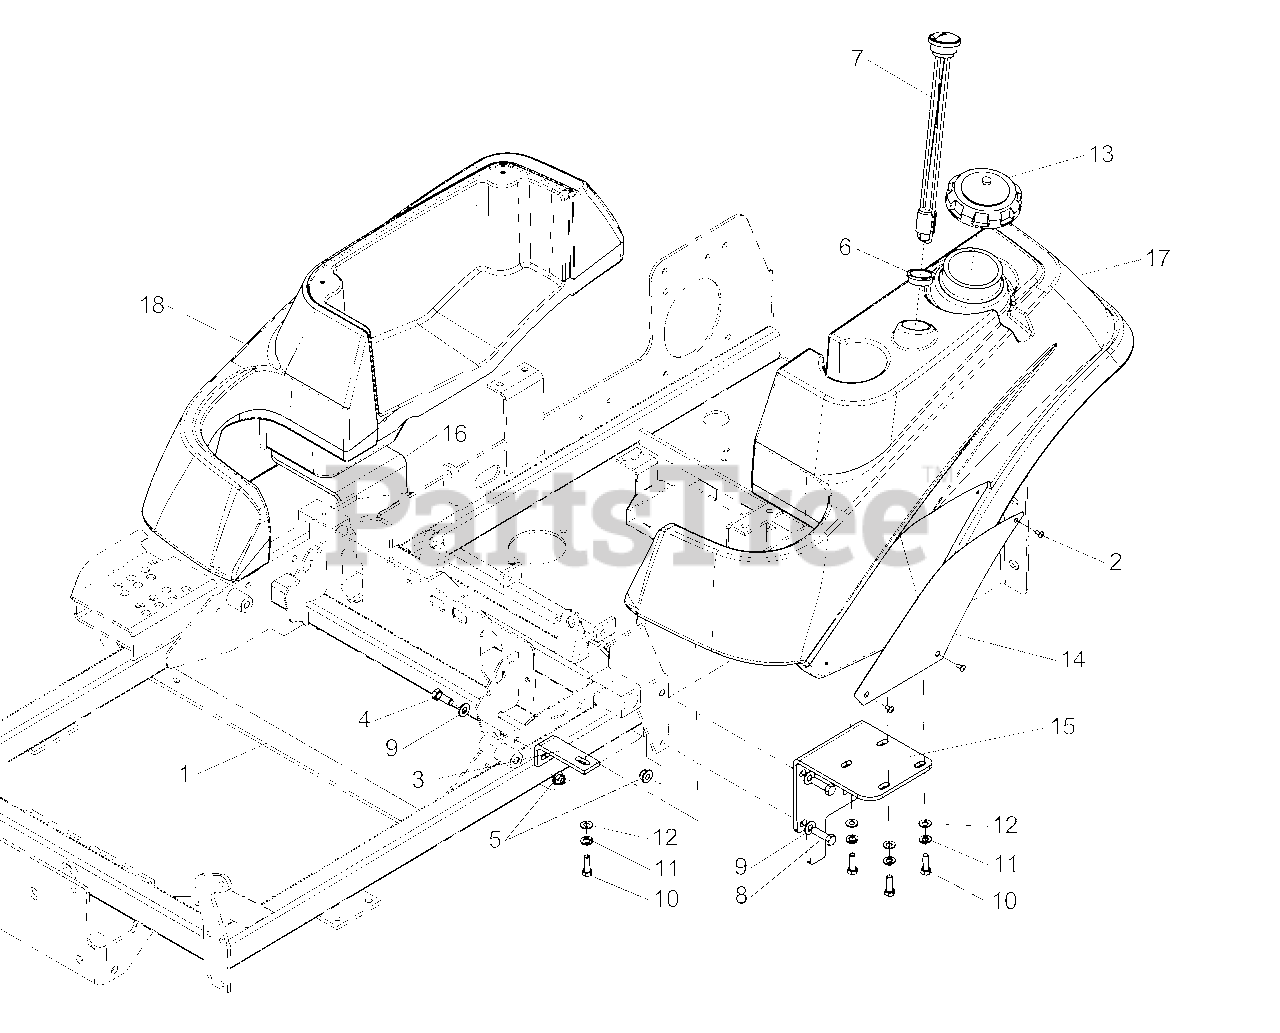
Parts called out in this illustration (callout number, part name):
1	MAIN FRAME (See Main Frame Group)
2	SCREW, Allen Head, #10-24 x 3/8"
3	MOUNT, TANK, FRONT - BLK
4	BOLT, 3/8-16 X 1" GD5
5	NUT, 3/8-16 Hex Nylock Flange
7	GAUGE, FUEL LEVEL
8	BOLT, 3/8-16 X 1-1/4"
9	WASHER 3/8" SAE
10	BOLT, 5/16-18 X 1"
11	WASHER, 5/16" Lock
12	WASHER, 5/16" SAE
13	CAP, FUEL TANK, 3-1/2" NECK
14	PLATE, BADGE
15	TANK MOUNT - LH
16	TANK MOUNT - RH
17	TANK, FUEL, CITATION/ZT400 - LH
18	TANK, FENDER, CITATION/ZT4000 - RH
